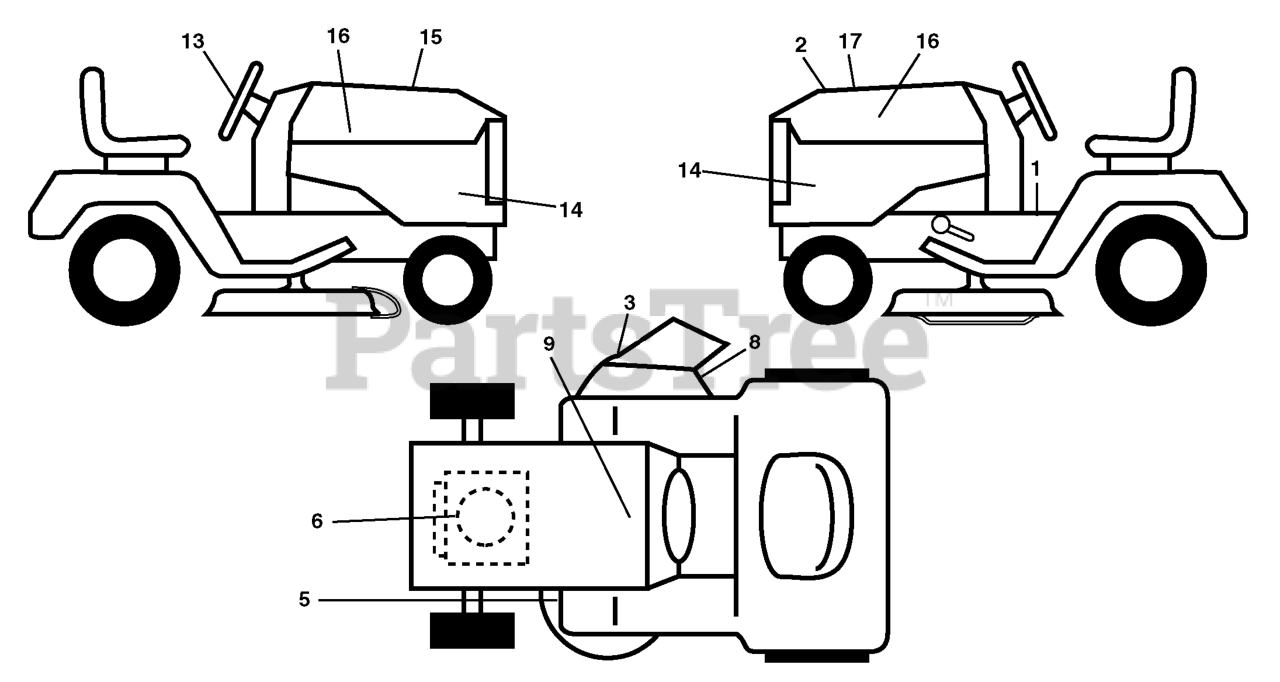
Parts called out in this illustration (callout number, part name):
1	DECAL.FENDER.OPER.TEX.
2	DECAL.HOOD.TOP.INSERT.
3	DECAL.WARN.KEEP.HAND.AWAY
5	DECAL CLUTCH/BRAKE
6	DECAL.ENG.B&S.24
8	DECAL.MOWER.SCH.48/54
9	DECAL BTRY SYMBOLS
13	DECAL.WHEEL.STRG.LGN.H
14	DECAL.PANEL.SIDE.YTH24
15	DECAL HOOD CUST. RESP.
16	DECAL.HOOD.NAMELOGO.HUSQ
17	DECAL.RPL.B&S.24HP.48"
